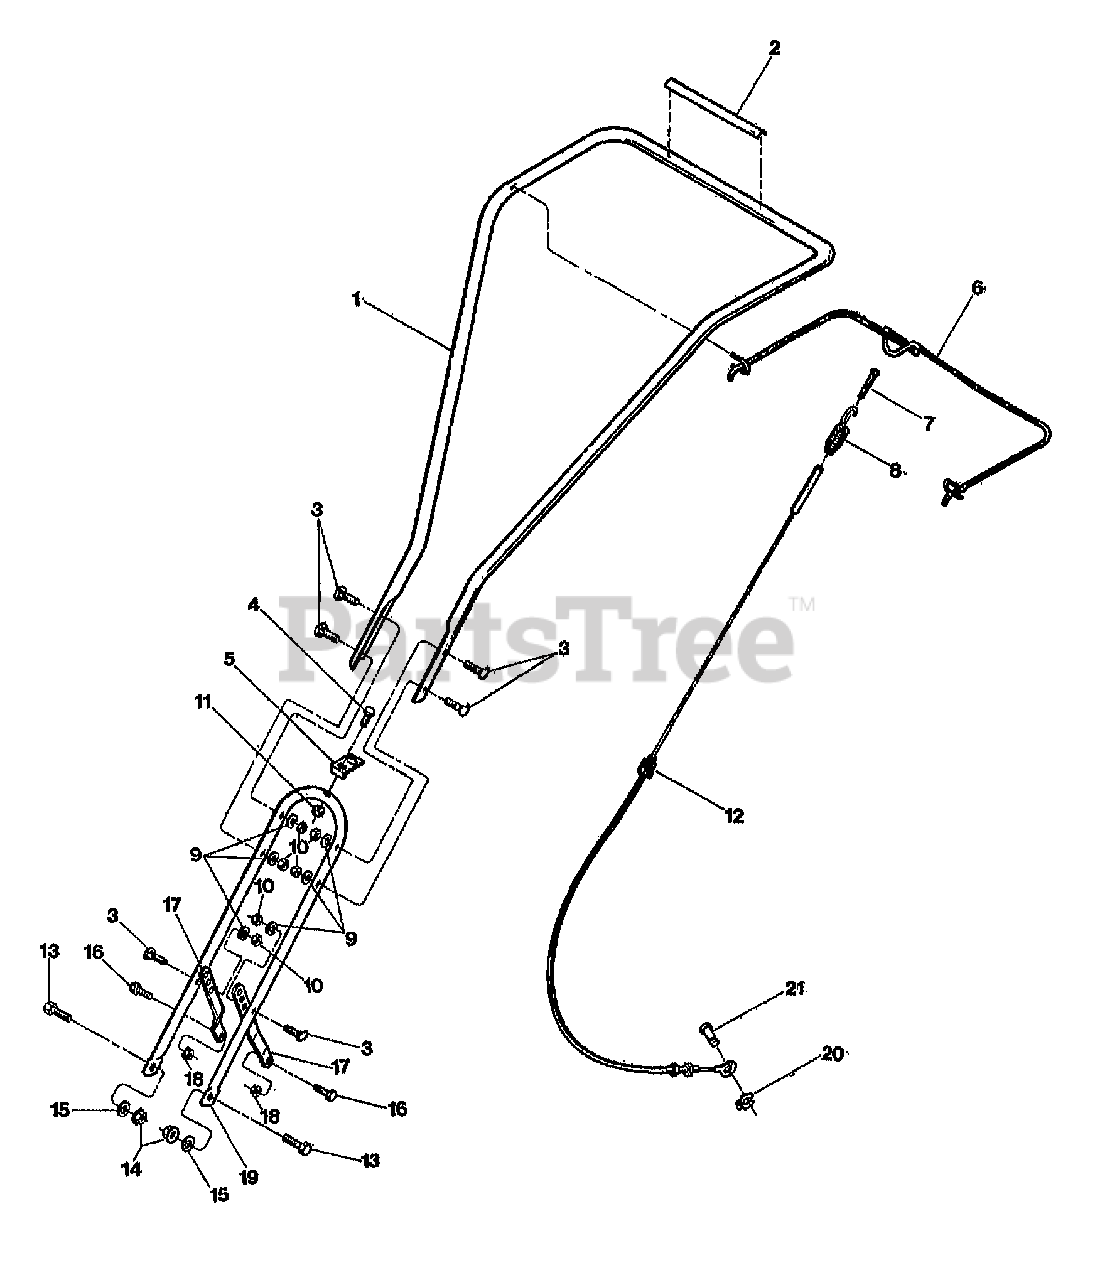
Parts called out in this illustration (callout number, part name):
1	HANDLEBAR-UPR W/DECAL
2	DECAL-FWD.CLUTCH LEVER
3	SCR-CUR.H.5/16X1 1/2
4	SCR-HH 1/4-20X1.25
5	TAB-CONDUIT MOUNT
6	BAIL-FWD. DRIVE PNT
7	SCR-SLOT.H.10-24X2
8	ASSM-SPRING CABLE
9	WASHER-LK .312 ZP
10	NUT-HEX 5/16-18 ZP
11	NUT-LK 1/4-20
12	ASSM-CONTROL CABLE
13	SCR-HH 3/8-16X.75 G5 ZP
14	NUT-LOCK 3/8-16 NYLON ZP
15	WASHER-FLAT 3/8 SAE
16	SCR-HH 5/16-18X.63 G5
17	LINK-H/BAR PNT
18	NUT-H/LK 5/16-18
19	HANDLEBAR-LWR PNT
20	RING-KLIP .188 DIA
21	PIN-CLEVIS CABLE
